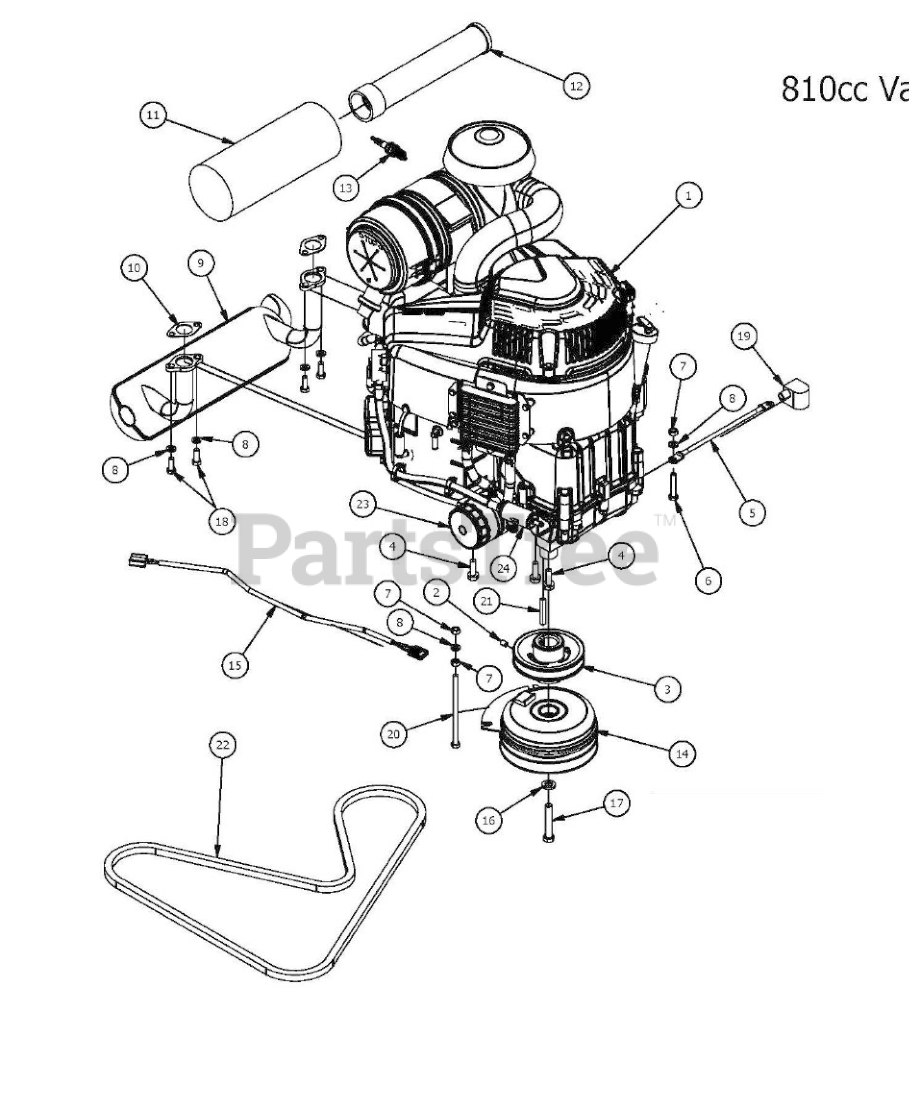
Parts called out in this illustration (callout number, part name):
1	810 Vanguard
2	3/8" Set Screw
3	4 3/4 Motor Pulley
4	3/8 x 1 1/8 bolt
5	Ground Cable
6	5/16" x 1 3/4" Hex Bolt
8	5/16" Lock Washer
9	Briggs Exhaust
10	Exhaust Gasket
11	Cani Filter- Ou
12	Canister Air Filter- Inner
13	Spark Plug
14	Clutch Assembly
15	Clutch Pigtail
16	7/16" Lock Washer
17	7/16" x 2 1/2" Hex Bolt
18	Torx Bolt-Exhaust
19	Black Boot For Ground Cable
20	5/16-18 x 5-1/2 GR 5 Hex Bolt
21	1/4 x 2 Square key Stock
23	Briggs Oil Filter
24	Universal Fuel Filter
